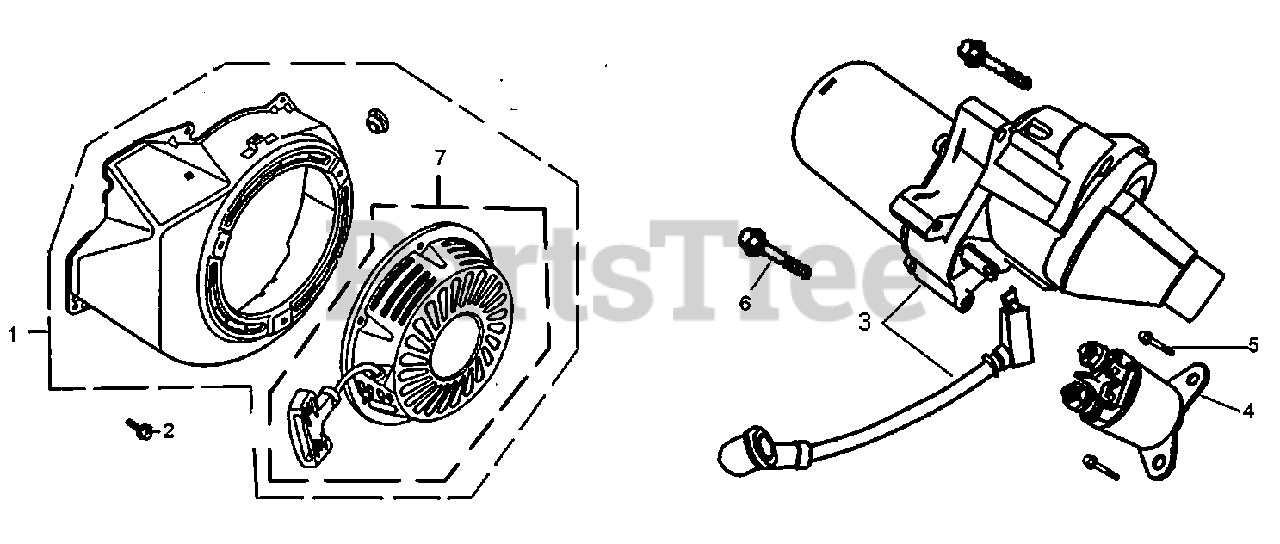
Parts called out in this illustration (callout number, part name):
1	STARTER ASSY. HW
2	BOLT, FLANGE, M6 X 12
3	STARTER MOTOR
4	CONTACTOR ASSY.
5	BOLT-WASHER, M6 X 14
6	BOLT, FLANGE, M8 X 35
7	ASSY, RECOIL STARTER HW (W/O BLOWER HOUSING)
